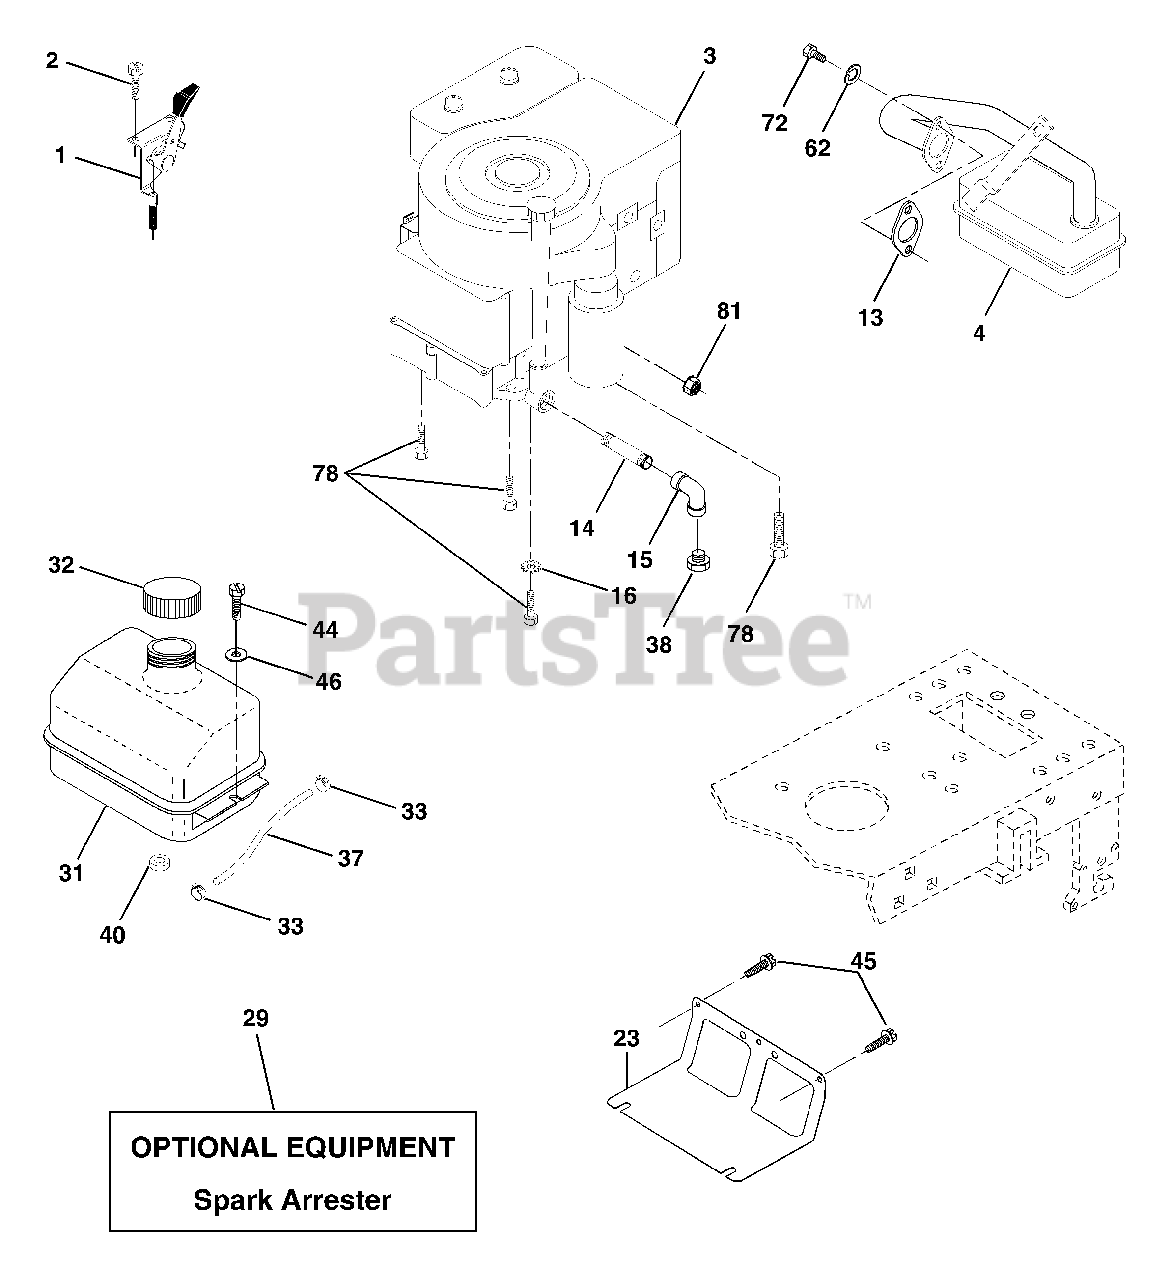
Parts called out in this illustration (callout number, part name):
1	Control Throt /Ch 23.5 Lh Flag
2	Screw Hex Thd Cut 1/4-20x5/8 T
4	Muffler Exhaust B&S Lt
13	Gasket 1 313 Id Tin Plated
14	Nipple Pipe 3/8 Npt X 3"
15	Elbow Std 90 Degree 3/8-18 Npt
16	Washer Lock Ext Tooth 3/8
23	Shield Browning/Debris Guard
29	Arrestor Spark
31	Tank Fuel 1 25 Fr
32	Cap Asm Fuel W/sym Vented
33	Clamp Hose Blk
37	Line Fuel 20"
38	Plug Oil Drain
40	Bushing Snap Nyl Blk Fuel Line
44	Screw Hexwsh Thdrol 1/4-20x3/4
45	Screw Hexwsh Thdr 3/8-16 x 3/4
46	Washer 9/32 X 7/8 X 16ga
62	Washer Lock Hvy Hlcl Spr 5/16
72	Screw Hexhd Cap 5/16-18x3/4
78	Screw 3/8-16x1-1/4
81	Nut Keps Hex 1/4-20 Unc
